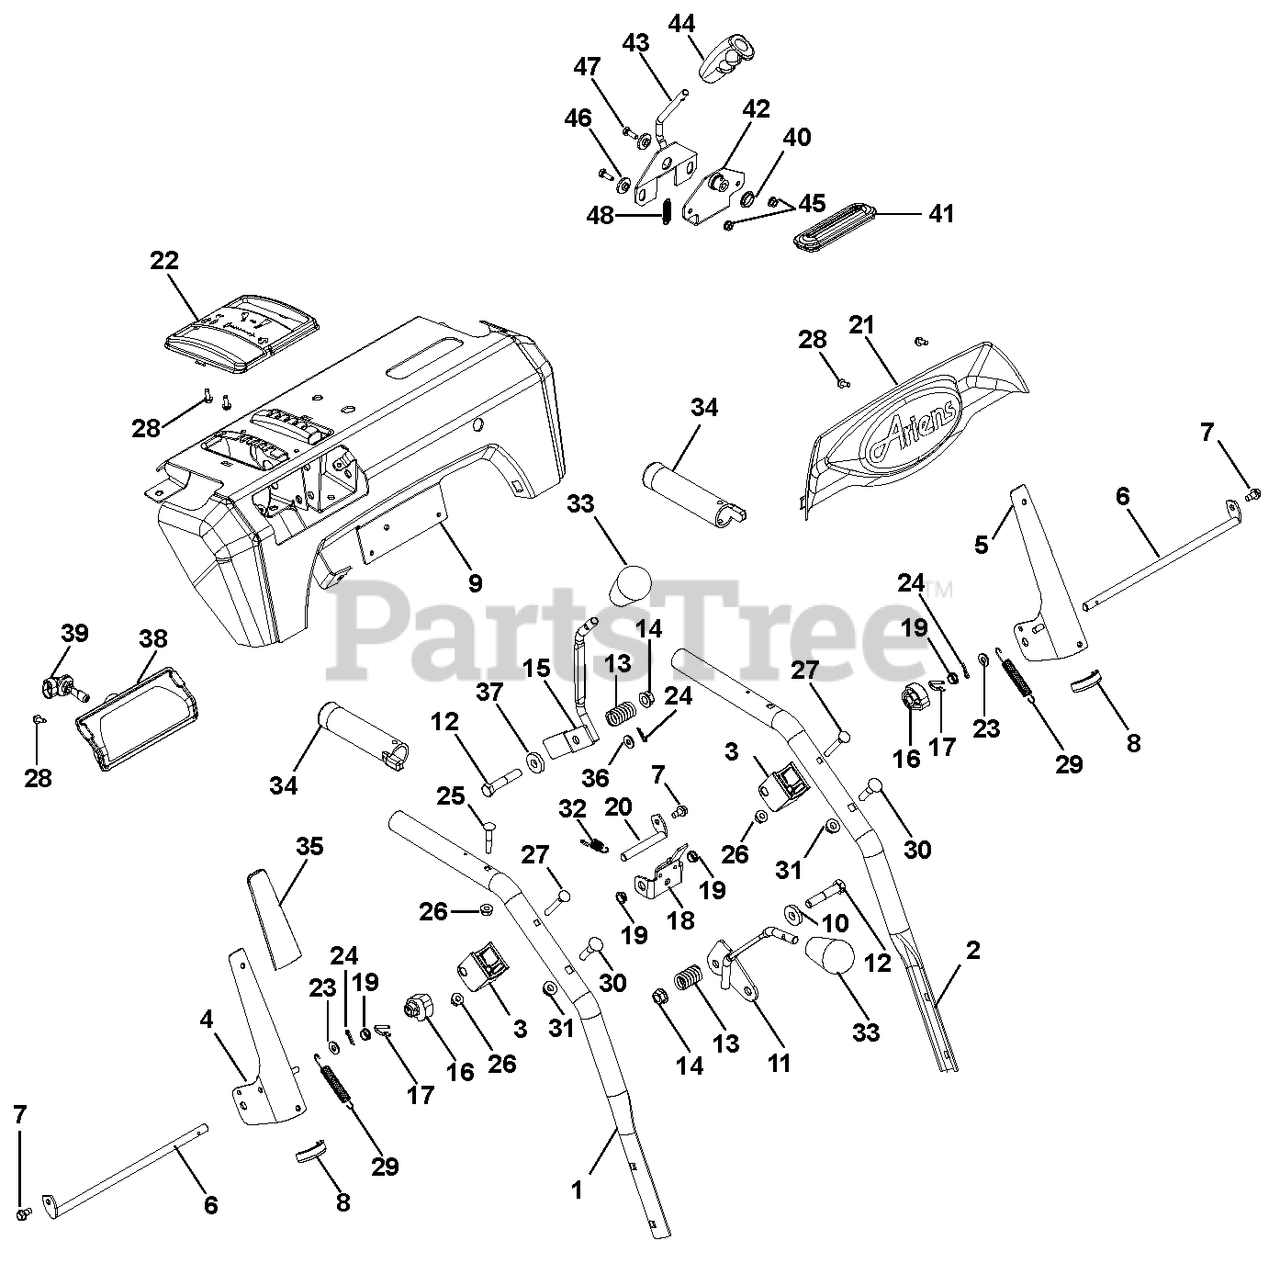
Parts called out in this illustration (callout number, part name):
1	HANDLEBAR, UPPER RH W/HW
2	HANDLEBAR, UPPER LH W/HW
3	BLOCK, CLUTCH PADDLE
4	LEVER, CLUTCH-RH
5	LEVER, CLUTCH-LH
6	ROD, PADDLE MOUNT - PRO
7	SCR-TAP .25-20X.50 HWH TR YWZ
8	EDGING, CLUTCH PADDLE - 2.00"
9	CTRL PANEL W/DECAL, PRO 12V
9	CTRL PANEL W/DECAL, QT HW ATC
9	CTRL PANEL W/DECAL, PRO TRACK
10	WSHR-FL-STL .406X1.00X.188 YWZ
11	WELDMENT, CONTROL LEVER(SHIFT)
12	@BLT-HEX .38-16X2.00 GR5 YWZC
13	SG-COMP .125X.781X1.250
14	@NUT-LK-TOP-FLG .38-16 YWZC
15	WELDMENT, CONTROL LEVER (DEFL)
16	CAM, INTERLOCK
17	PIN, SPRING CLIP
18	BRACKET, INTERLOCK ARM
19	BUSHING, POLYLINER-.38 SNAPIN
20	ROD, PIVOT - INTERLOCK
21	DASH BEZEL, ARIENS LOGO - PRO
22	BEZEL, SHIFT
23	@WSHR-FL-STL.281X.62X.065 YWZC
24	PIN-HAIR INT .06X.18X.77
25	BLT-RDHDXLSQNK.25-20X1.25 G5ZC
26	@NUT-LK-TOP-FLG .25-20 YWZC
27	BLT-RDHDXLSQNK .25-20X2.0 G5YZ
28	SCR-TAP #10X.50 BOSS INDHXHD
29	SPRING, EXTENSION
30	@BLT-RDHDSQNK .31-18X1.50 G5YZ
31	@NUT-LK-TOP-FLG .31-18 YWZC
32	SPRING-EXT .047X.438X1.45
33	KNOB,SOFT TEARDROP,PUSH-ON GRY
34	HEATED GRIP, MAGURA
35	CLUTCH PADDLE SLEEVE - GRAY
36	BSHG-SLV .265X.500X.219
37	WSHR-FL-STL .380X1.50X.062 YWZ
38	HEADLIGHT ASSY, HALOGEN 20W
39	BULB, LIGHT-HALOGEN 20W
40	BUSHING, POLYLINER-.75 SNAPIN
41	GROMMET-BOOT, QUICKTURN
42	MOUNT, CHUTE CONTROL
43	LEVER, CHUTE CONTROL
44	CONTROL HANDLE, QUICK TURN
45	@NUT-LK-TOP-FLG .25-20 YWZC
46	BSHG-FLG .265X.448X.243X1.00
47	@BLT-HEX .25-20X.75 GR5 YWZC
48	SG-TENS .048X.44X1.75 WLD 9
